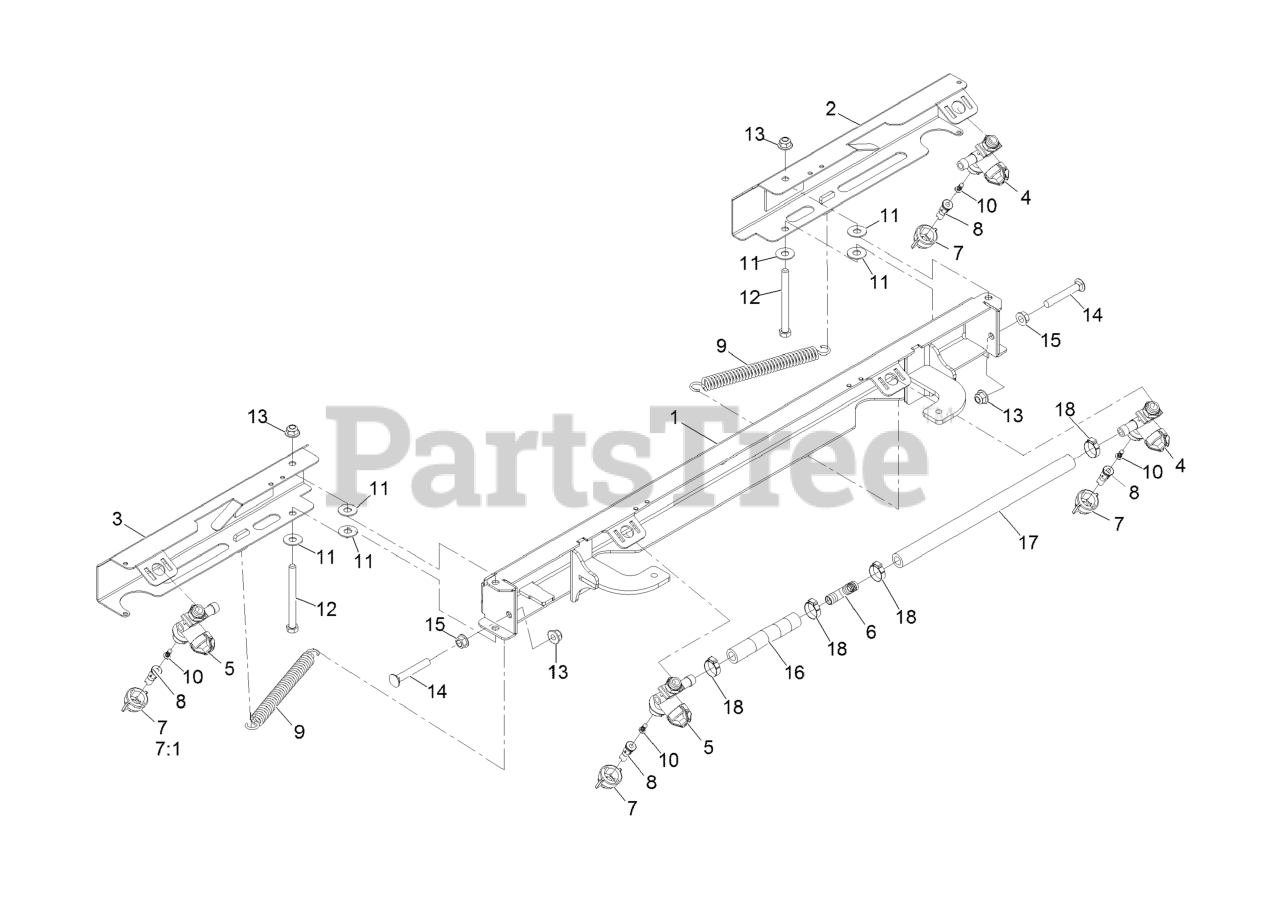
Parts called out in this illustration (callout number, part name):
1	Boom-Center
2	Boom-Wing, Rt
3	Boom-Wing, Lt
4	BODY-NOZZLE, RIGHT
5	BODY-NOZZLE, LEFT
6	FITTING-TEE, BARB
7	CAP-NOZZLE
7:1	SEAT-GASKET
8	TIP-SPRAY, 025
9	SPRING-EXTENSION
10	STRAINER-NOZZLE, 50M 5PSI
11	WASHER-FLAT
12	SCREW-HH
13	Nut-Hex Flange
14	SCREW-CARR
15	Nut-Hex Flange
16	Hose-Spray
17	Hose-Spray
18	CLAMP-OETIKER, 167
